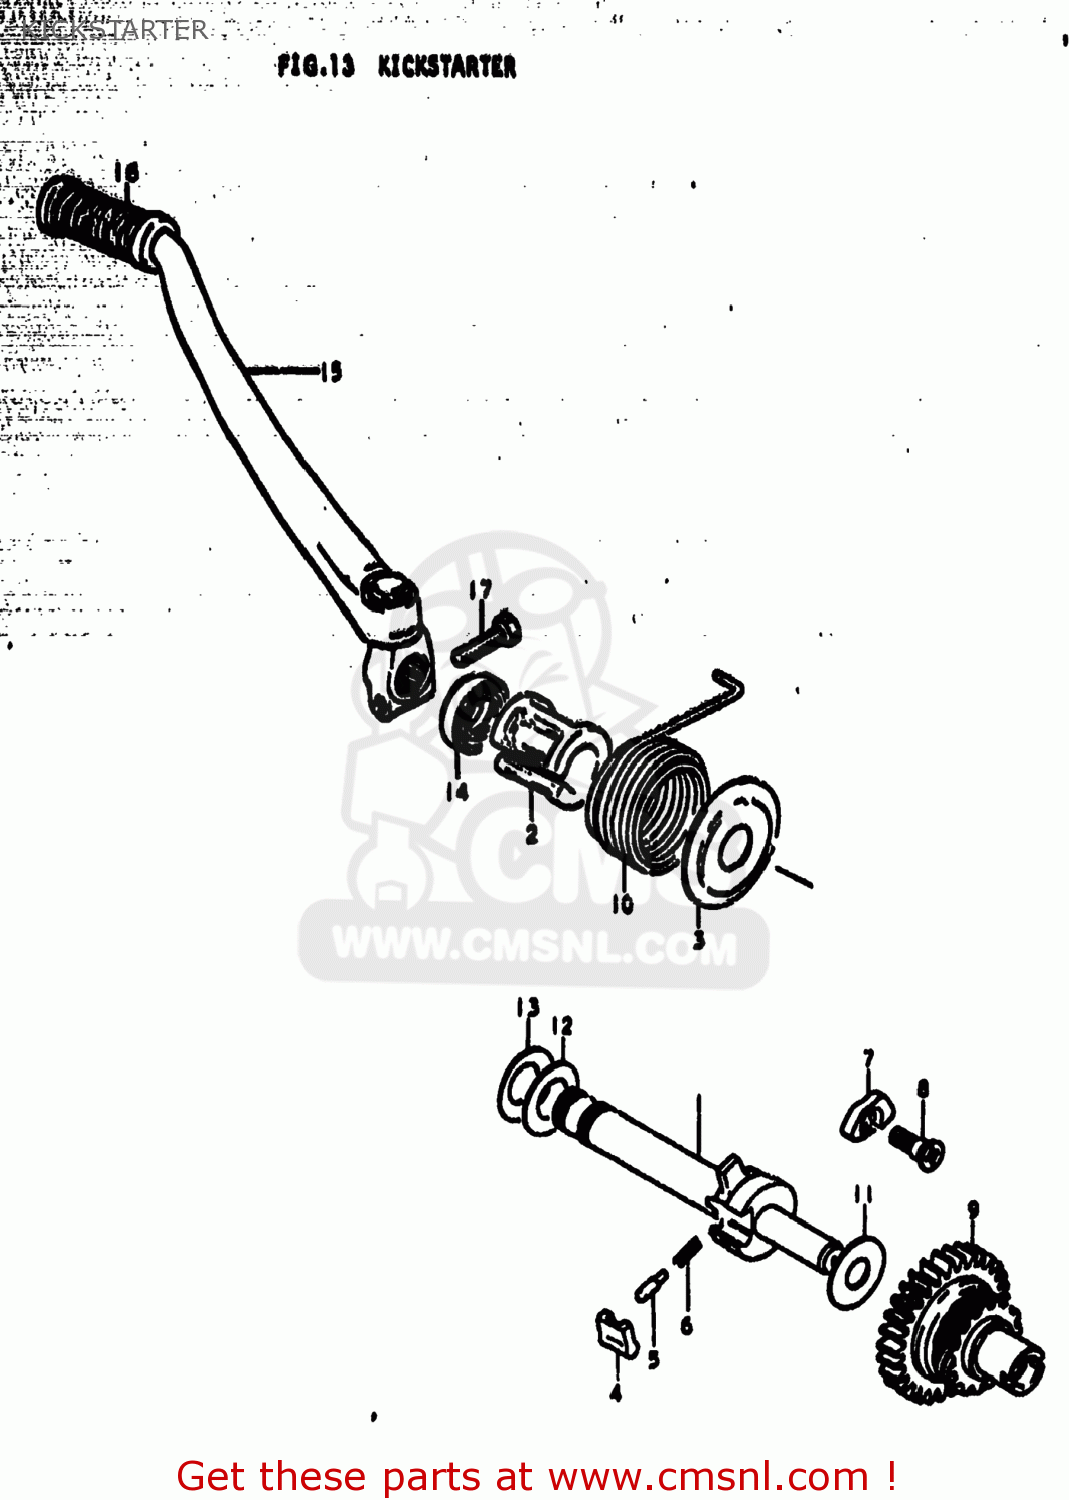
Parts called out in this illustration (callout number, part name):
1	SHAFT,KICK STARTER
2	GUIDE,KICK STARTER SFT SPRING
3	HOLDER,KICK STARTER SHAFT SPR
4	PAWL,KICK STARTER
5	PIN(5X15.5)
6	SPRING
7	LIFTER,KICK STARTER PAWL
8	SCREW(6X19)
9	GEAR,KICK STARTER DRIIVE
10	SPRING
11	WASHER(12X30X3)
12	WASHER(16X30X0.5)
13	WASHER
14	SEAL,OIL(16X30X8)
15	LEVER ASSEMBLY,KICK STARTER
16	RUBBER,KICK STARTER PEDAL
17	BOLT
